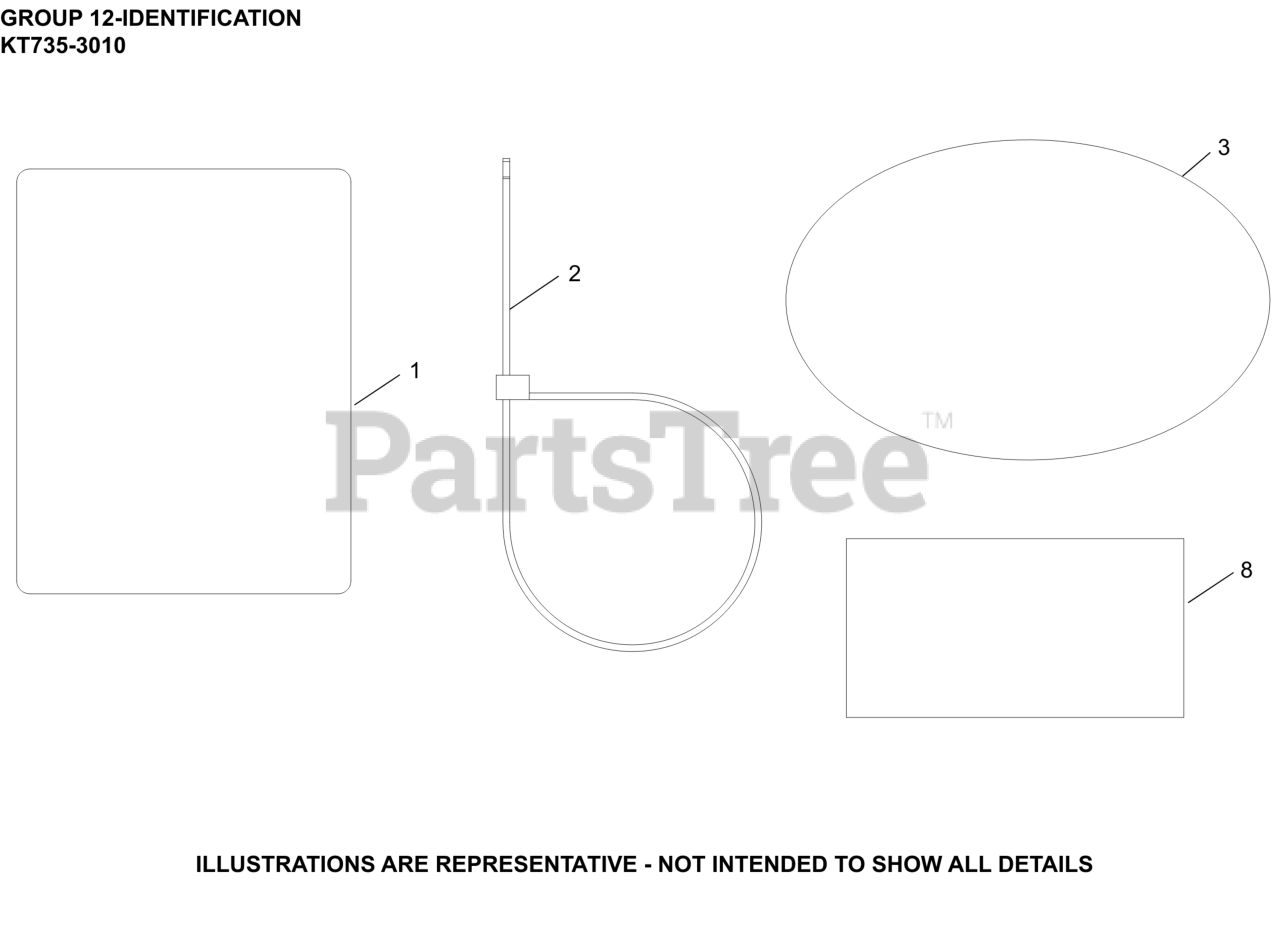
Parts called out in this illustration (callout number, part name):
1	LABEL, CLEAR LAMINATION
3	LABEL, 7000 SERIES (24HP, PRO)
3	LABEL, PRO PERFORMANCE FILTRATION SYSTEM
8	DECAL, USA
